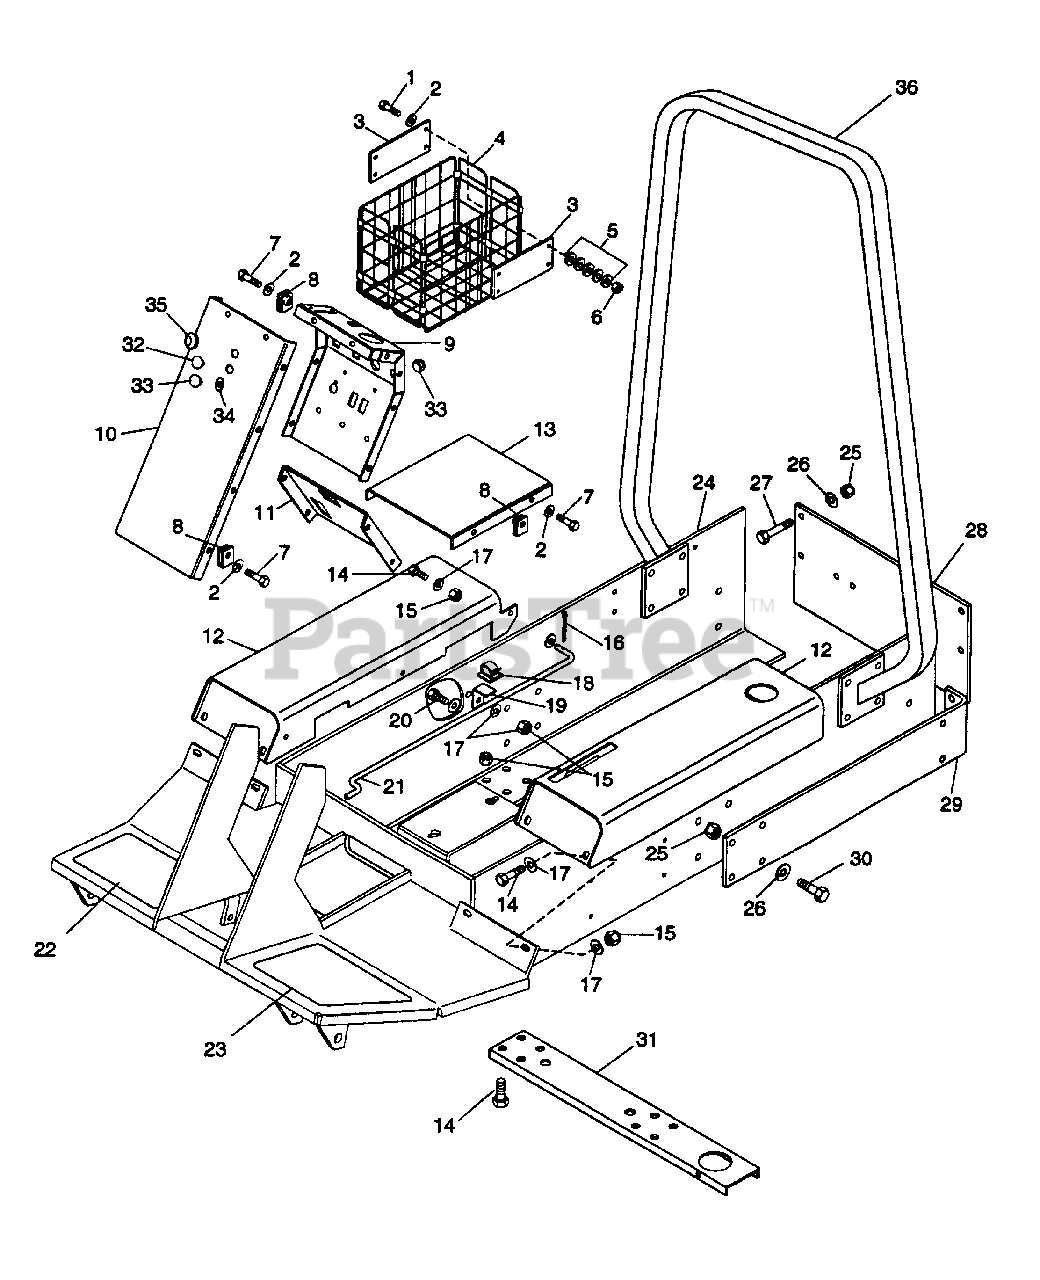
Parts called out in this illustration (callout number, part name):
1	BLT-HEX .25-20 X 1.50 PL GR 5
2	WSHR-FL-STL .563 X .375 X .109
3	STRP-BASKET
4	BASKET
5	WSHR-FRICTION .750 X .256 X .100
6	NUT-LK-NYL .250-20 PL
7	SCR-MCH .25-20 PAN HD
8	NUT-RTNR .25-20 X .56
9	PNL, INST SILK SCREEN
10	PNL, FRONT
11	PNL, BRAKE LOCK SILK SCRN
12	WLDMT, FENDER R.H.
12	WLDMT, FENDER L.H.
13	PLT, ACCESS SILKSCREEN
13	PNL, ACCESS SILKSCREEN
14	BLT-HEX .380-16 X .875
15	NUT-LK-NYL .375-16 PL
16	PIN-COTR .09 X .75 PL
17	WSHR-FL-STL .406 X .812 X .065
18	CLIP, WIRE
19	BRKT, STAY ROD
20	BLT-HEX .38-16 X 1.00 PL GR 5
21	ROD, STAY
22	CVR, R.H. FOOT
23	CVR, L.H. FOOT
24	WLDT, FRAME
25	NUT-LK-NYL .50-13 PL
26	WSHR-FL-STL .531 X 1.062 X .095
27	BLT-HEX .50-13 X 1.50 PL GR 5
27	BLT-HEX .50-13 X 2.25 PL GR 5
28	PLT, BUMPER
30	BLT-HEX .50-13 X 1.25 PL GR 5
30	BLT-HEX .50-13 X 1.75 PL GR 8
31	BR, FRAME
32	HOLE PLUG
33	PLUG, HOLE
34	WSHR-FL-STL .328 X 1.0 X .094 PL
35	GROMMET
36	WLDMT, ROLLOVER BAR
NS	DECAL, DANGER HAND
NS	DECAL, CORNER
NS	DECAL SET, PM 400
